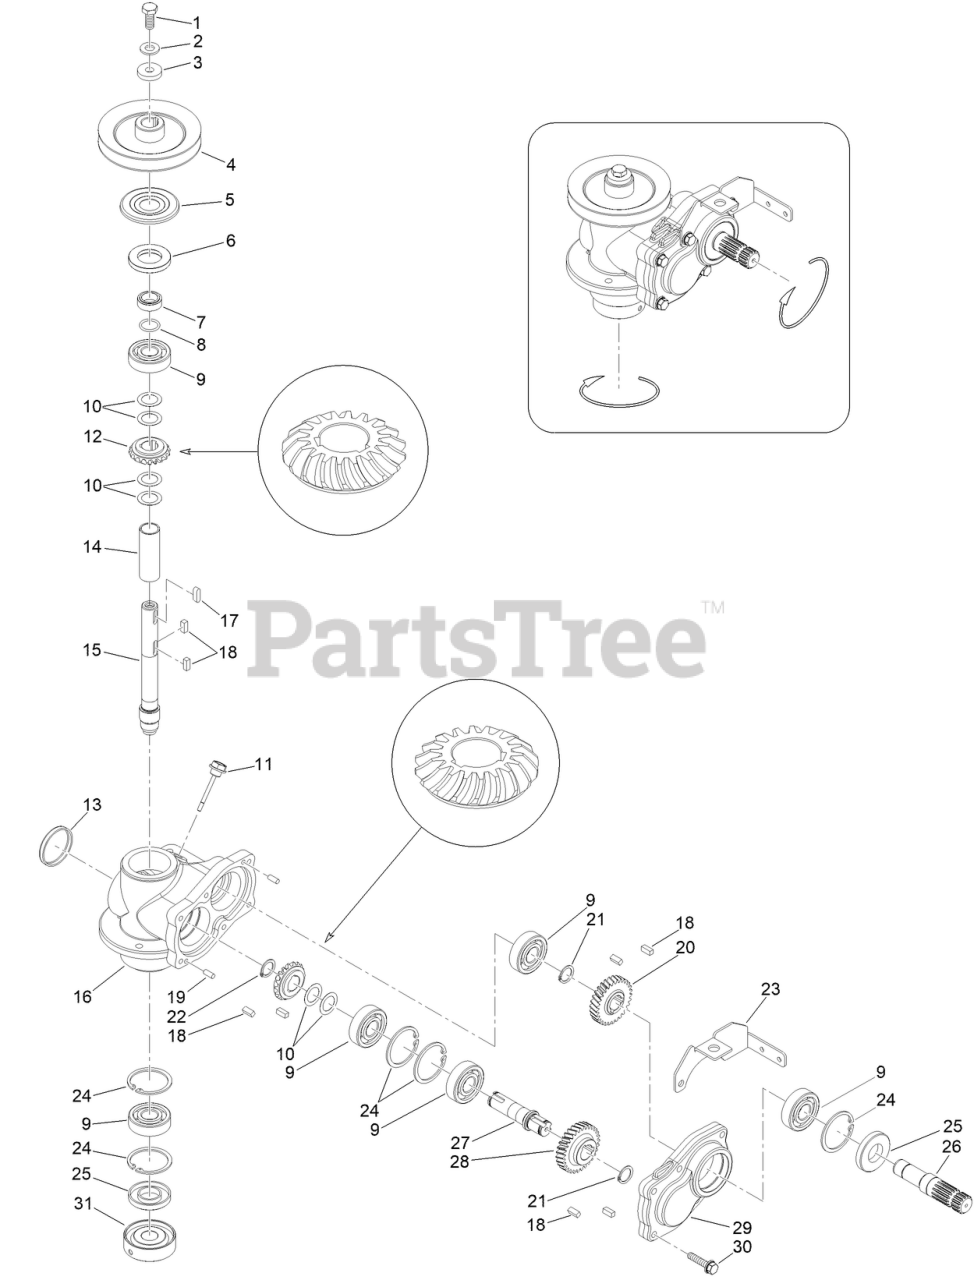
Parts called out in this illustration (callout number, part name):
2	WASHER
3	WASHER
4	PULLEY, BLADE SHAFT
5	GUARD, DECK GEARBOX
6	OIL SEAL
7	RING, DECK GEARBOX
8	O-RING,
9	BEARING
10	SPACER
11	DIPSTICK, TRANSMISSION
12	SPIRAL BEVEL GEAR, LH
14	SPACER
15	SHAFT, LH BLADE
16	GEARBOX, DECK
18	KEY-SHAFT
20	GEAR, HELICAL-LH
21	RING-RETAINING, INT
22	SPIRAL BEVEL GEAR, RH
23	SUPPORT, CARDAN SHAFT COVER
24	RING-RETAINING, INT
25	SEAL, OIL
26	SHAFT, PRIMARY DECK GEARBOX
27	SHAFT, SECONDARY DECK GEARBOX
28	GEAR, HELICAL-LH
29	COVER, DECK GEARBOX
30	SCREW-HHF
31	SUPPORT, BLADE
